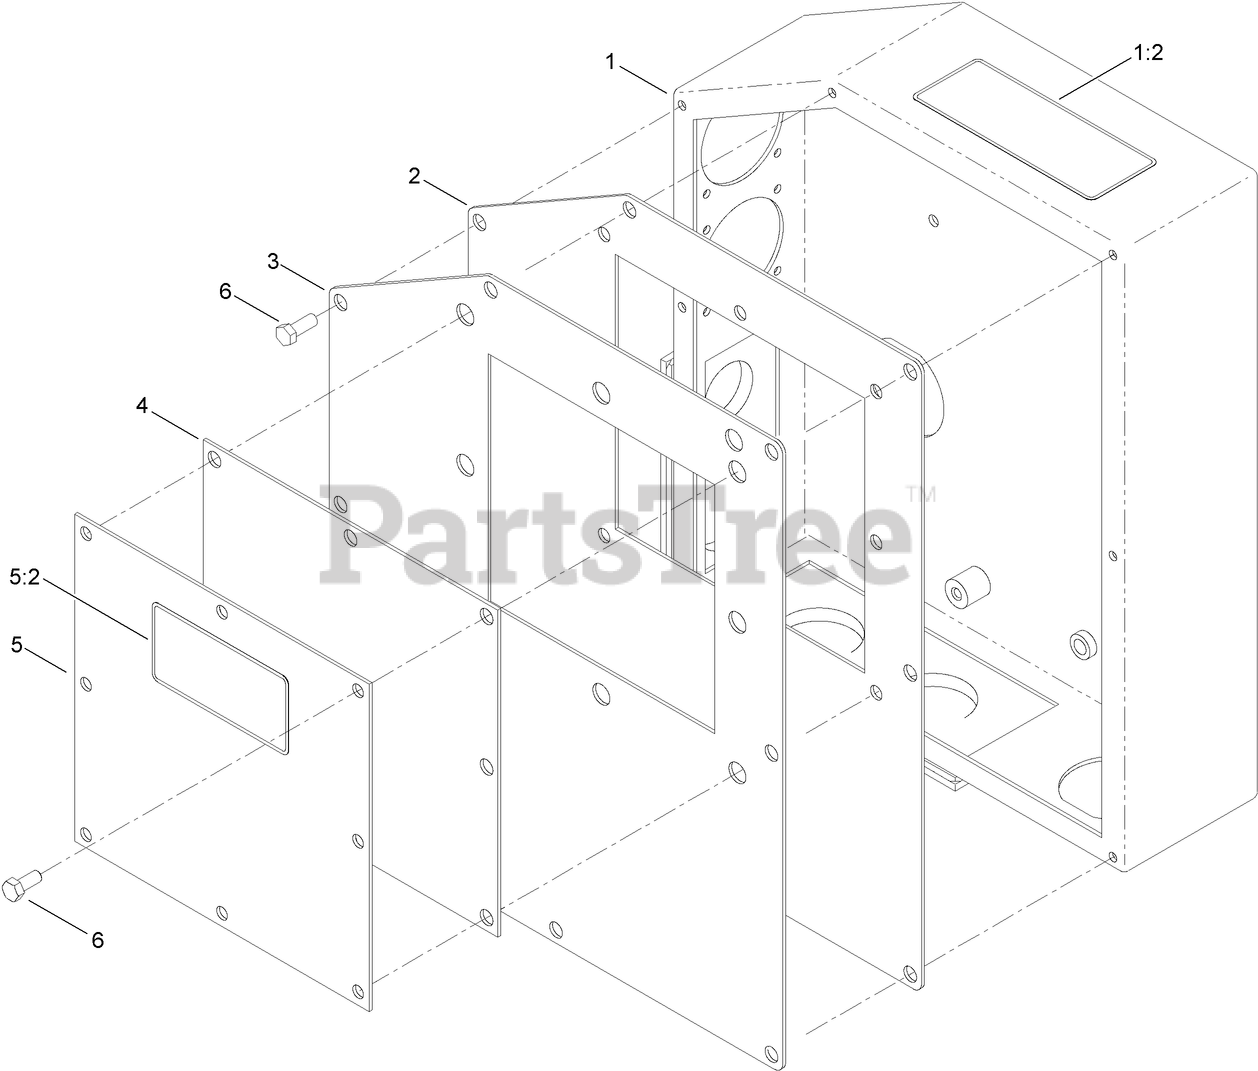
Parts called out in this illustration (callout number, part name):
1	ELECTRIC JUNCTION BOX
1:2	DECAL-CAUTION, ELECTRONICS
2	GASKET-BOX, JUNCTION (MAIN)
3	COVER-BOX, JUNCTION (MAIN)
4	GASKET-BOX, JUNCTION (AUXILLARY)
5	AUXILLARY ELECTRIC COVER ASM
5:2	DECAL-CAUTION, FUSE REPLACEMENT
6	SCREW-HH
